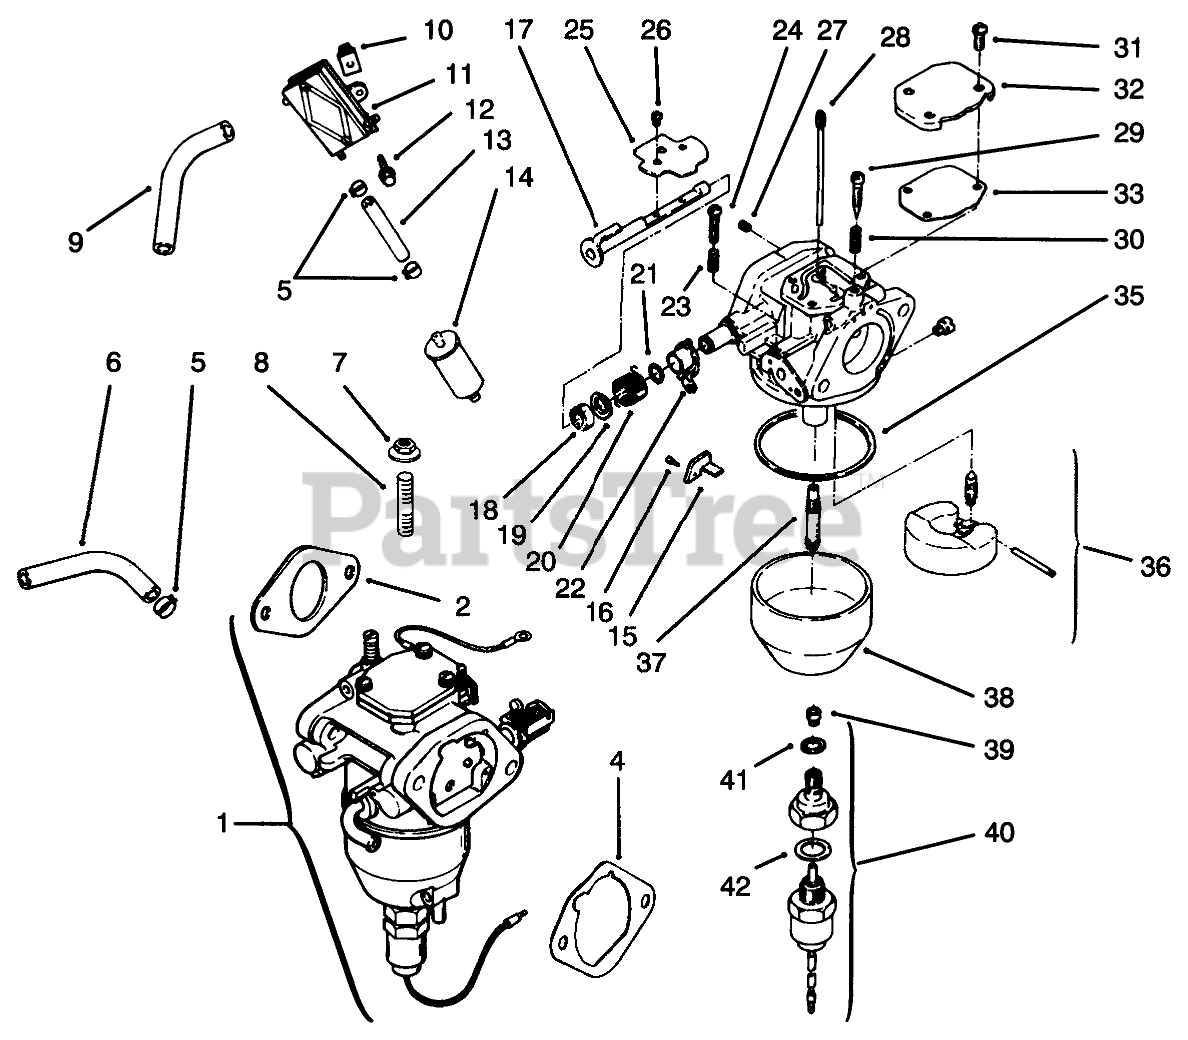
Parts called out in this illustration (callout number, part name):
1	Kit-Carb INCL 2/4/15-42 (Only On: 72103)
2	Gasket-Carburetor (Only On: 72103)
4	Gasket-A/C Base (Only On: 72103)
5	Clamp-Hose (Only On: 72103)
6	Line-Fuel 10 1/2" (Only On: 72103)
7	Nut M6x1.0 (Only On: 72103)
8	Stud M6x1.0x95 (Only On: 72103)
9	Line-Fuel 12" (Only On: 72103)
10	Nut-Plastic (Only On: 72103)
11	Pump-Fuel (Only On: 72103)
12	Screw-Cable Clip (Only On: 72103)
13	Line-Fuel 31/2" (Only On: 72103)
14	Filter-Fuel (Only On: 72103)
15	Bracket-Throttle Stop (Only On: 72103)
16	Screw M2.5x45x5.5 (Only On: 72103)
17	Shaft-Choke (Only On: 72103)
18	Washer (Only On: 72103)
19	Collar-Choke (Only On: 72103)
20	Spring-Choke Return (Only On: 72103)
21	Ring-Choke Lever (Only On: 72103)
22	Lever-Choke (Only On: 72103)
23	Spring-Throttle Screw (Only On: 72103)
24	Screw-Throttle Adjust (Only On: 72103)
25	Valve-Choke (Only On: 72103)
26	Screw-Throttle Shaft (Only On: 72103)
27	Jet-Air Bleed (Only On: 72103)
28	Jet-Slow (Only On: 72103)
29	Screw-Idle Adjust (Only On: 72103)
30	Spring-Idle Adjust Screw (Only On: 72103)
31	Screw (Only On: 72103)
32	Cover-Passage (Only On: 72103)
33	Gasket-Passage Cover (Only On: 72103)
35	Gasket-Float Chamber (Only On: 72103)
36	Kit-Float Repair (Only On: 72103)
37	Nozzle-Main (Only On: 72103)
38	Chamber-Float (Only On: 72103)
39	Jet-Main (Only On: 72103)
40	Kit-Solenoid INCL 41-42 (Only On: 72103)
41	Gasket-Chamber Screw (Only On: 72103)
42	Gasket-Solenoid (Only On: 72103)
